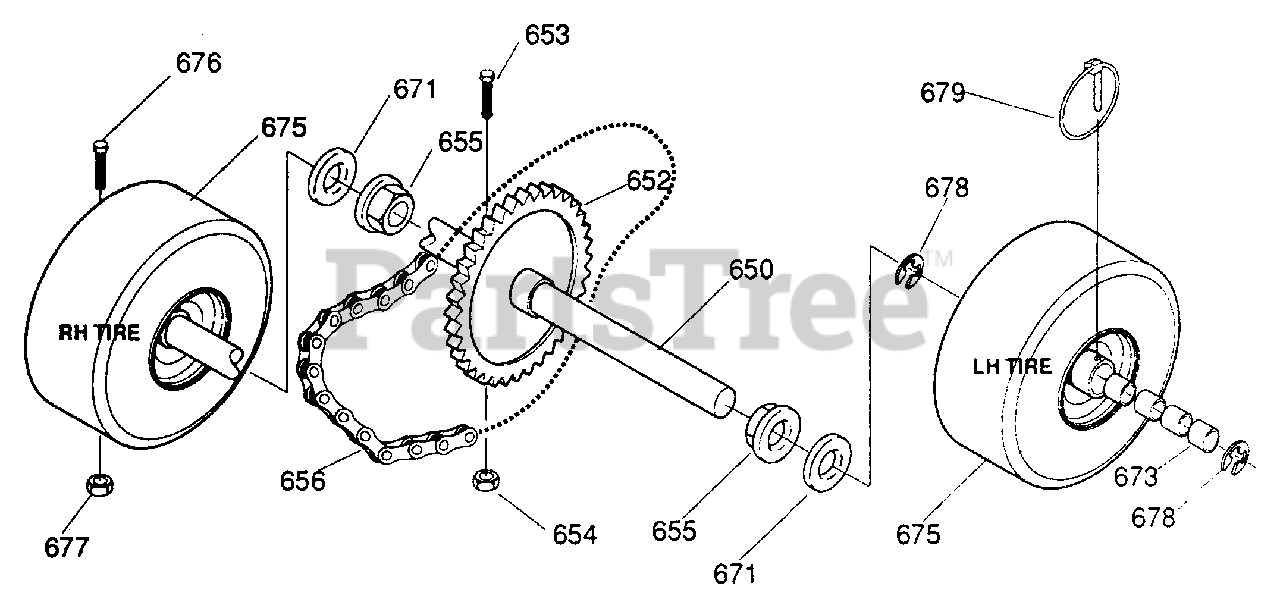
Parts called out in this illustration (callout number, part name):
650	SHAFT, AXLE
652	SPRKT HUB #40-35T x .75 ID
653	SCREW, 1/4-20 x 2.25
654	NUT, 1/4-20 REGHEXCTRLK
655	BEARING, FL .755 ID x 1.127 OD x .75
656	CHAIN, ROLLER #42 x 40PITCHES
671	FLATWASHER,.765 x 1.12 x .06
673	BEARING, FLANGE
675	TIRE & RIM, PU 13 x 5.O x 6
676	SCREW, SHR 1/4-20 x 1.75
677	NUT, 1/4-20 REGHEXCTRLK
679	PIN, KLIK.25 x 1.38 DIA
